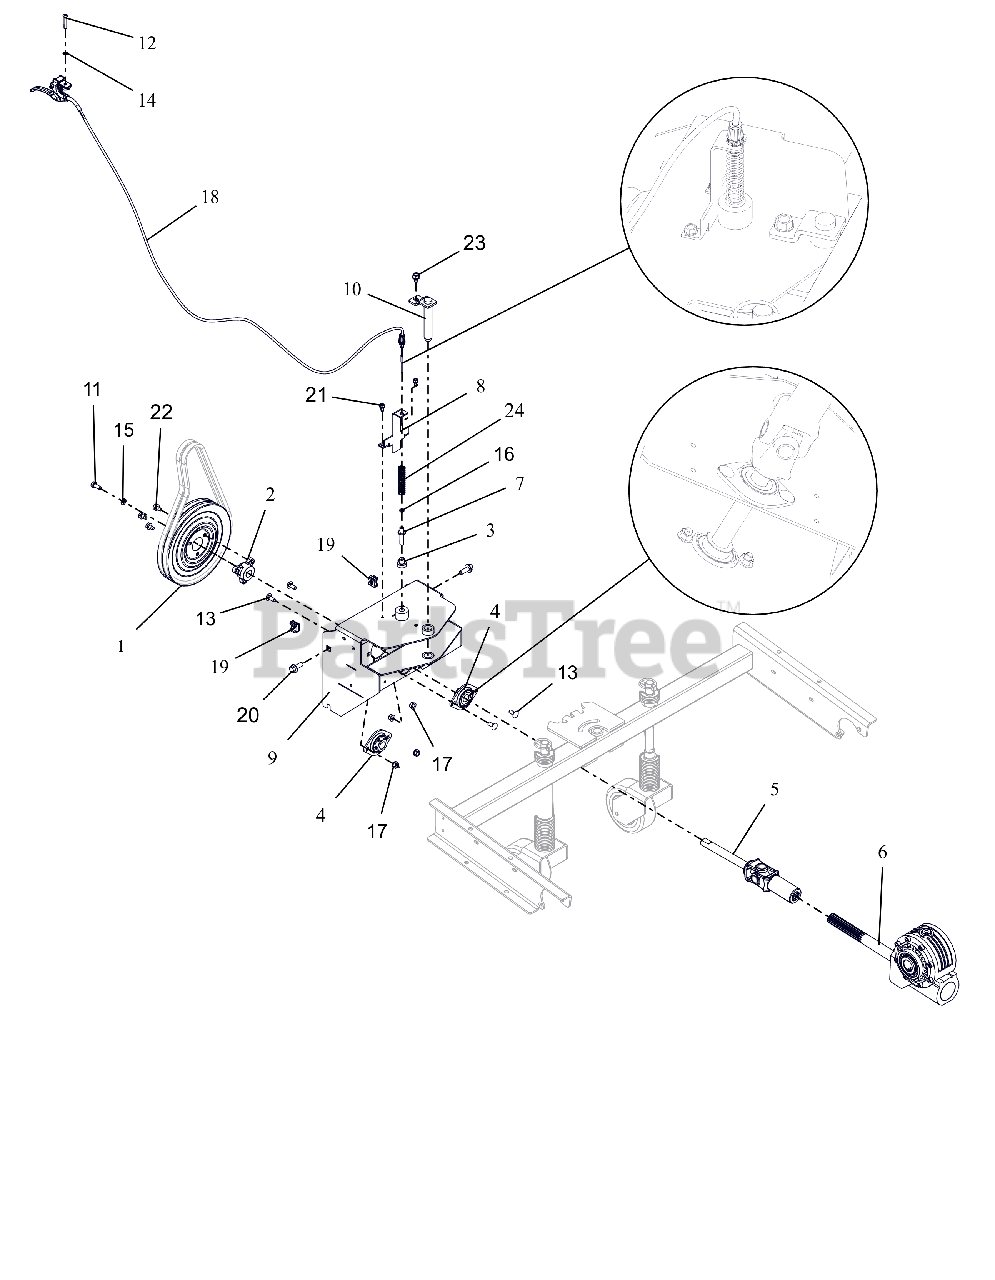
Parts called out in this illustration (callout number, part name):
1	PULLEY, SPIN FORM DUAL GROOVE
2	PULLEY HUB, BOLT-ON D-BORE .75
3	SPACER -FLANGED .390X.500X.781
4	BEARING, 2 BOLT FLANGE -.75 ID
5	DRIVELINE, SERIES 07 (U-JOINT)
6	GEARBOX, WORM - 8.25:1
7	PIN, ADJUSTABLE ANGLE BRUSH
8	BRKT, PIN HOLDER
9	ADAPTER, BRUSH
10	WLDMT, BRUSH PIN
11	BLT, HEX .31-24X.750 G5 ZCC
12	SCR-MCH .25-20X1.50 OVAL HD
13	BLT,RHSN .31-18X.75 G5 ZCC
14	WSHR-LK-INT .250 TH TYA
15	WSHR, LK-HVY .312X.097 ZCC
16	NUT, HEX #10-24 ZCC
17	NUT-LK-TOP-FLG .312-18 GF ZCC
18	CABLE, REMOTE BRUSH LOCK
19	NUT-RETNR .38-16 TINRMAN
20	BLT, SERHFWH .38-16X1.00 ZCC
21	SCR-TAP .25-20X.50 HWH ZCC
22	SCR,TAP .312-18X.50 HWH TR ZCC
23	SCR,TAP .375-16X.50 HWH TR ZCC
24	SPRING, COMPRESSION
